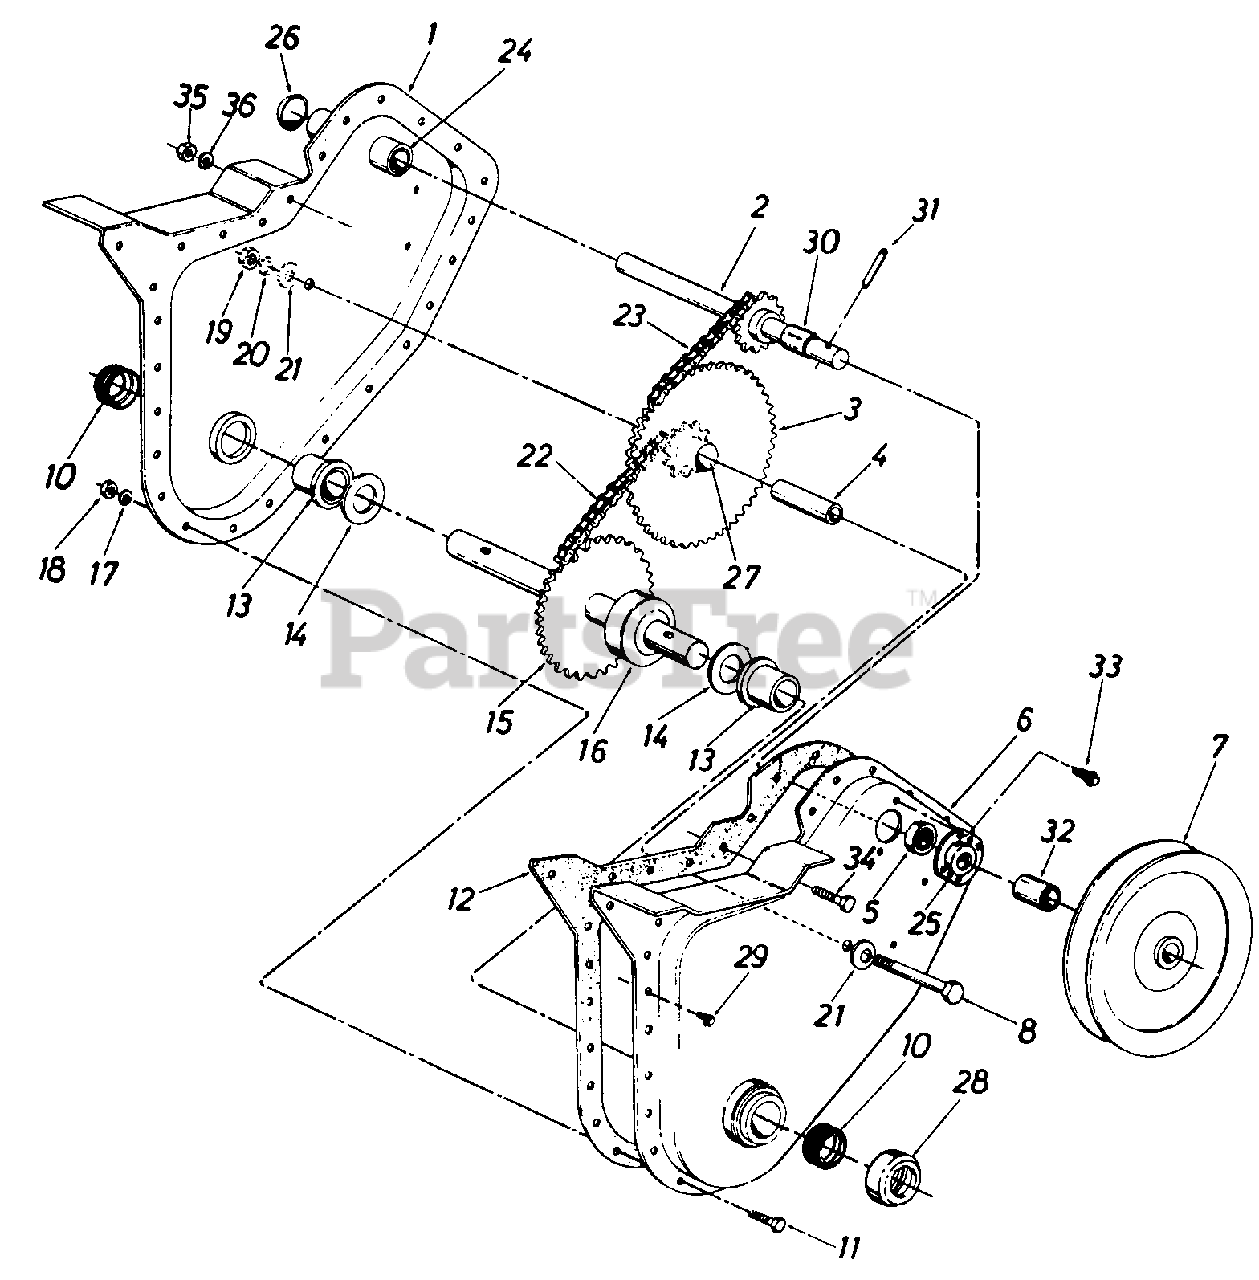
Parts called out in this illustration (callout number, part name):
1	HOUSING-CHAIN-CASE RH
2	SHAFT ASSY-INPUT
3	SPROCKET & HUB ASSY
4	BEARING-INNER RACE
5	BEARING-BALL
6	CHAIN CASE HSG-LH
8	SCREW-HEX 3/8-24 X 2.50
11	SCREW-HEX 1/4-28 X .62
12	GASKET
13	BEARING-FLANGE
14	WASHER-FL-.88 X 1.50 X .030
15	SHAFT ASSY-TINE
16	SPACER
17	LOCK WASHER 1/4 DIA
18	NUT-HEX 1/4-28
19	NUT-HEX INS L-3/8-24
20	WASHER-LOCK-3/8
21	WASHER-BELL .3/8ID X 1.12OD X .030
22	#420 CHAIN 1/2 PITCH X 38 LINKS
23	#35 CHAIN 3/8 PITCH X 50 LINKS
25	HOUSING-BRG
26	PLUG-EXPANSION
27	BEARING-SLEEVE
29	SCREW-HEX WASH SF TAPP
31	PIN-SPRING SPIRAL 1/4X1.5 HEAVY DT
33	SCREW-TAP 1/4-20 X .38
